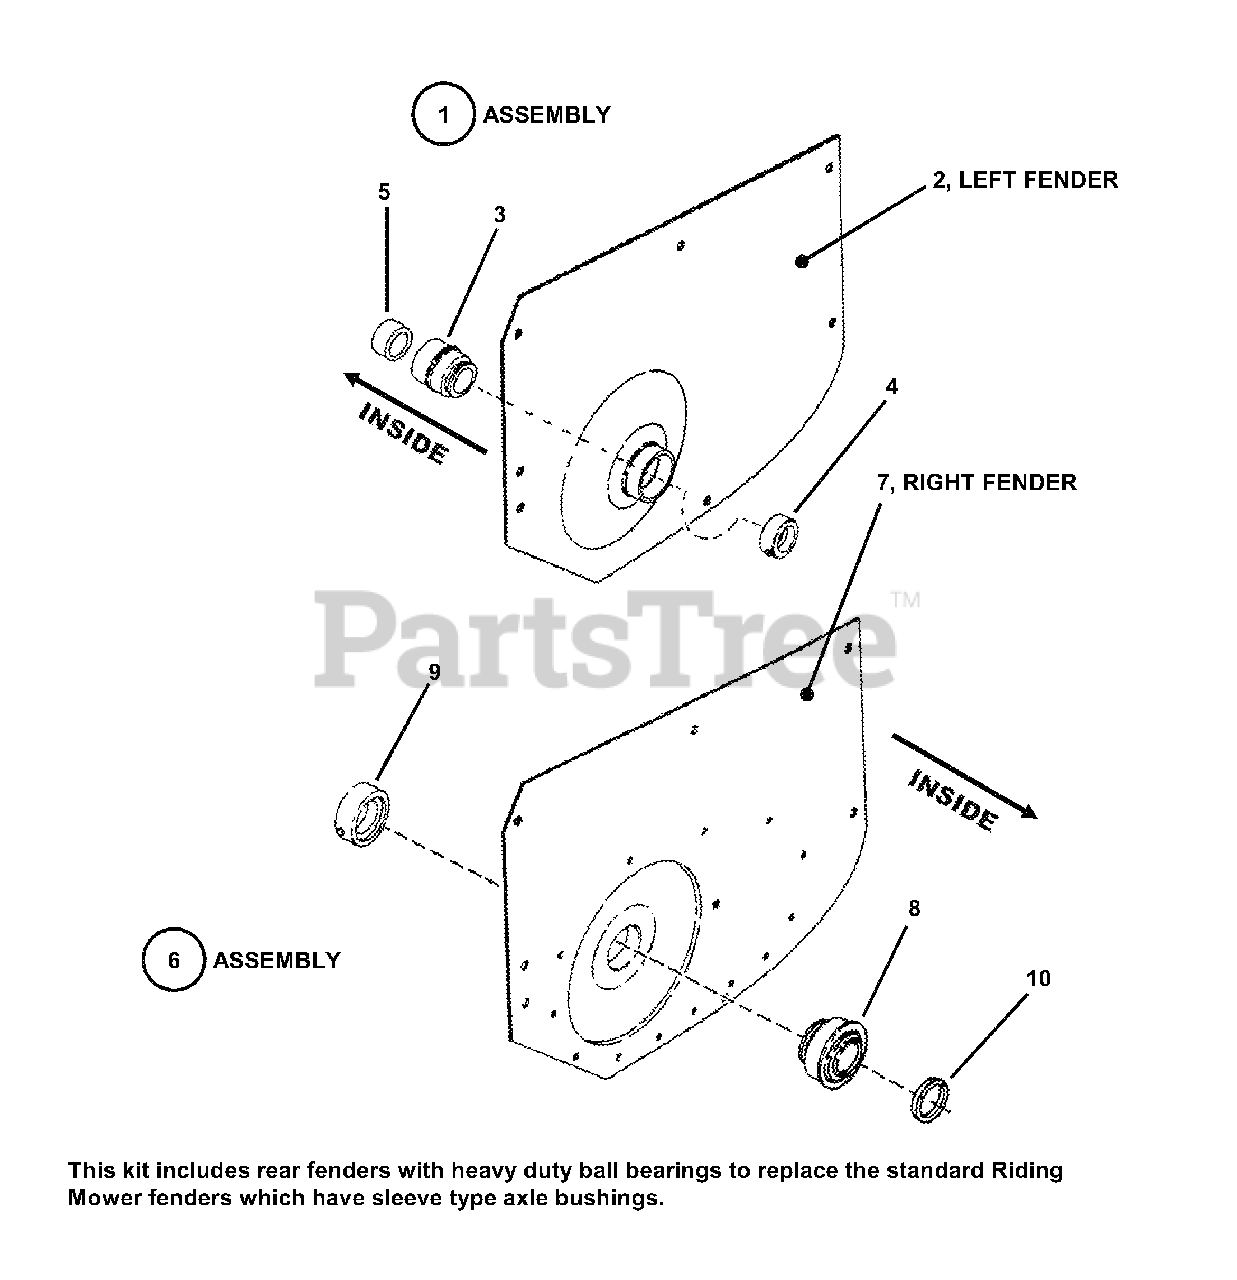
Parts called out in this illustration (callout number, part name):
1	ASSEMBLY, Left Fender and Bearing
2	FENDER, Left Side (Extra Tough)
3	BALL BEARING, Left Side
4	LOCK COLLAR
5	SPACER, Left Hand
6	ASSEMBLY, Right Hand Fender and Bearing
7	FENDER, Right Side (Extra Tough)
8	BALL BEARING, Rear Axle
9	LOCK COLLAR
10	SPACER, Short Axle
